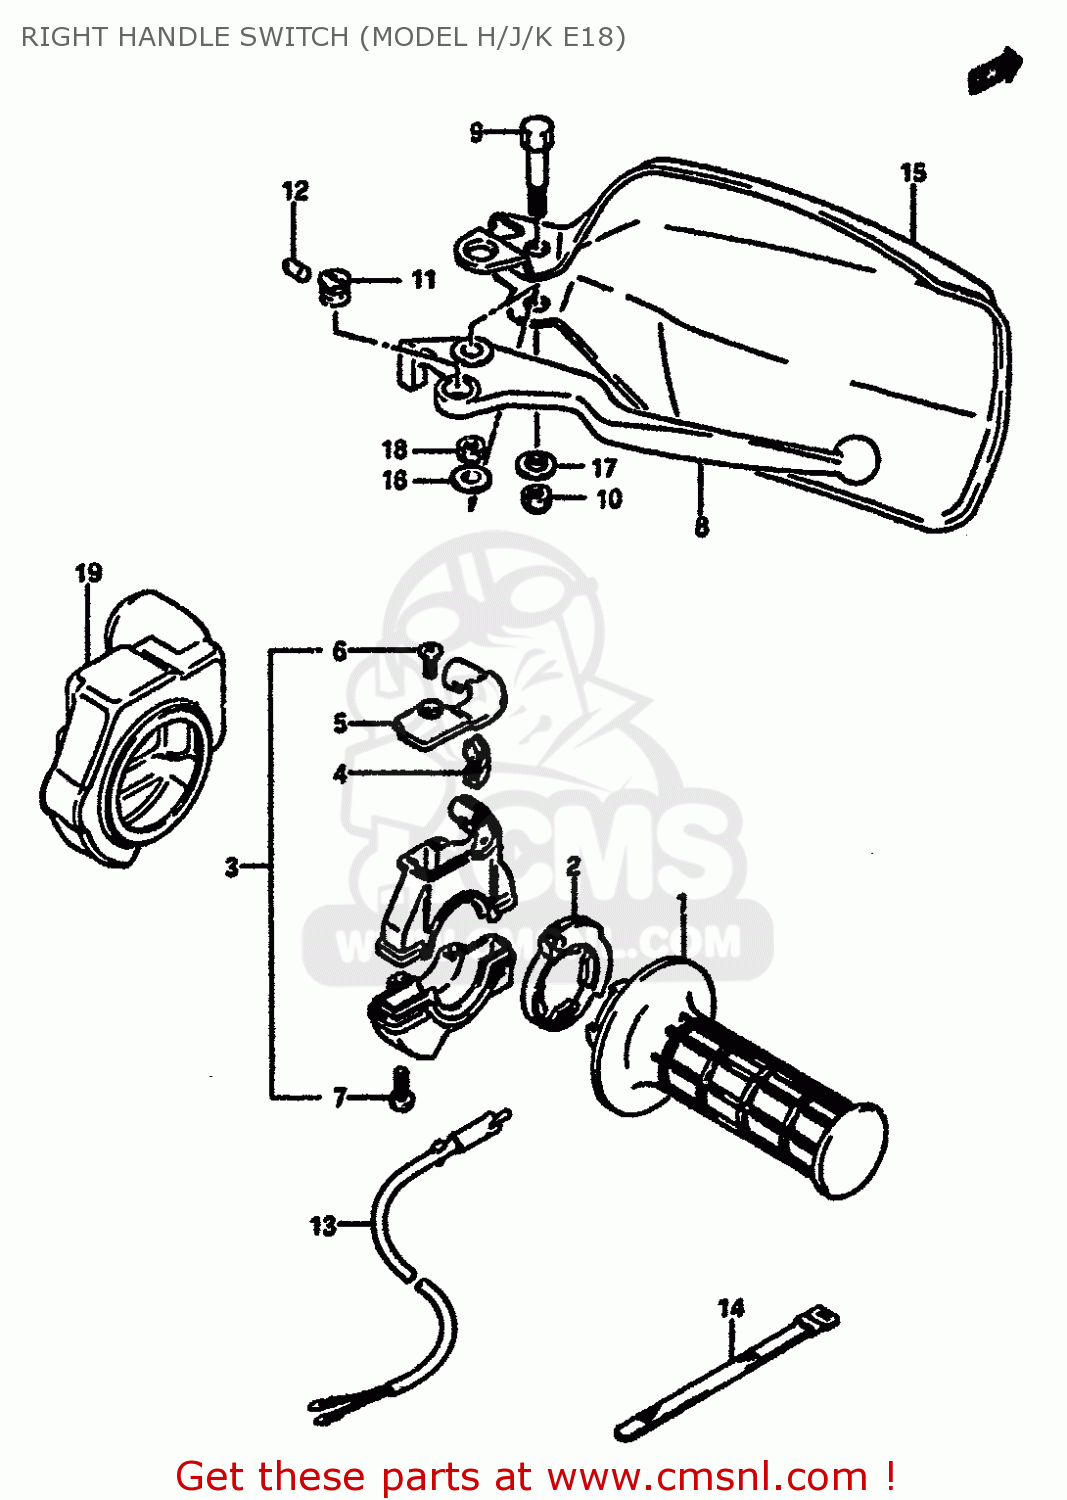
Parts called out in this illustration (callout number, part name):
1	GRIP,THROTTLE
2	ROTOR,THROTTLE GRIP
3	CASE ASSY,THROTTLE
4	GUIDE PIECE,THROTTLE
5	COVER,THROTTLE CASE
6	SCREW
7	SCREW
8	LEVER,BRAKE
9	BOLT,LEVER PIVOT
10	NUT
11	ADJUSTER
12	ROD,PUSH
13	SWITCH ASSY,STOP
14	CLAMP(L:120)
15	COVER,KNUCKLE,
16	WASHER(6.5X16X1.2)
17	WASHER
18	NUT 6MM
19	COVER,THROTTLE CASE
